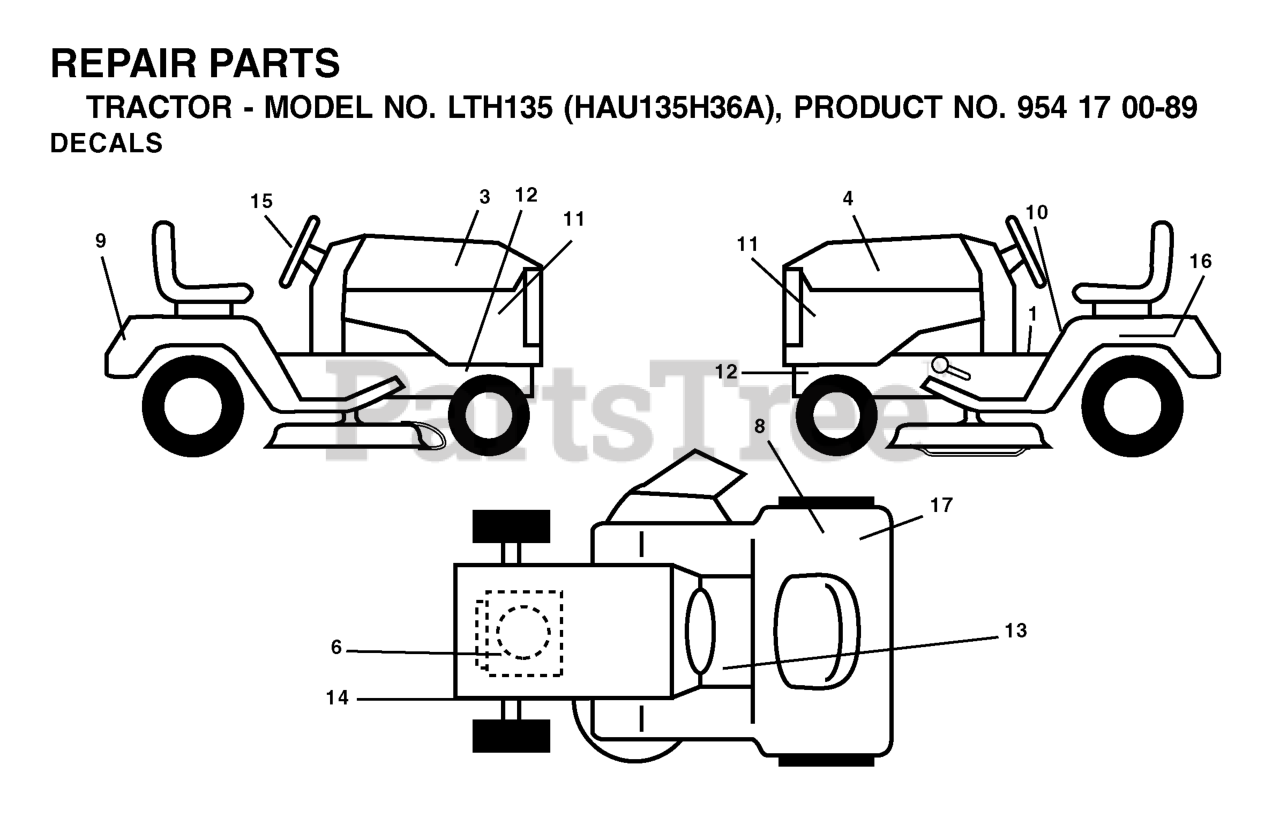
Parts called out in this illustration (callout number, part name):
1	DECAL READ OWNER'S MAN SYMS
8	DECAL
9	DECAL FENDER HUSQ
10	DECAL PARK BRAKE
11	DECAL PNL SIDE
13	DECAL
14	DECAL V-BELT SCHEMATIC
15	DECAL.WHEEL.STEERING.HUSQ.PERM
16	DECAL BTRY SYMBOLS
17	DECAL.INTERNATIONL.CUTFINGER
